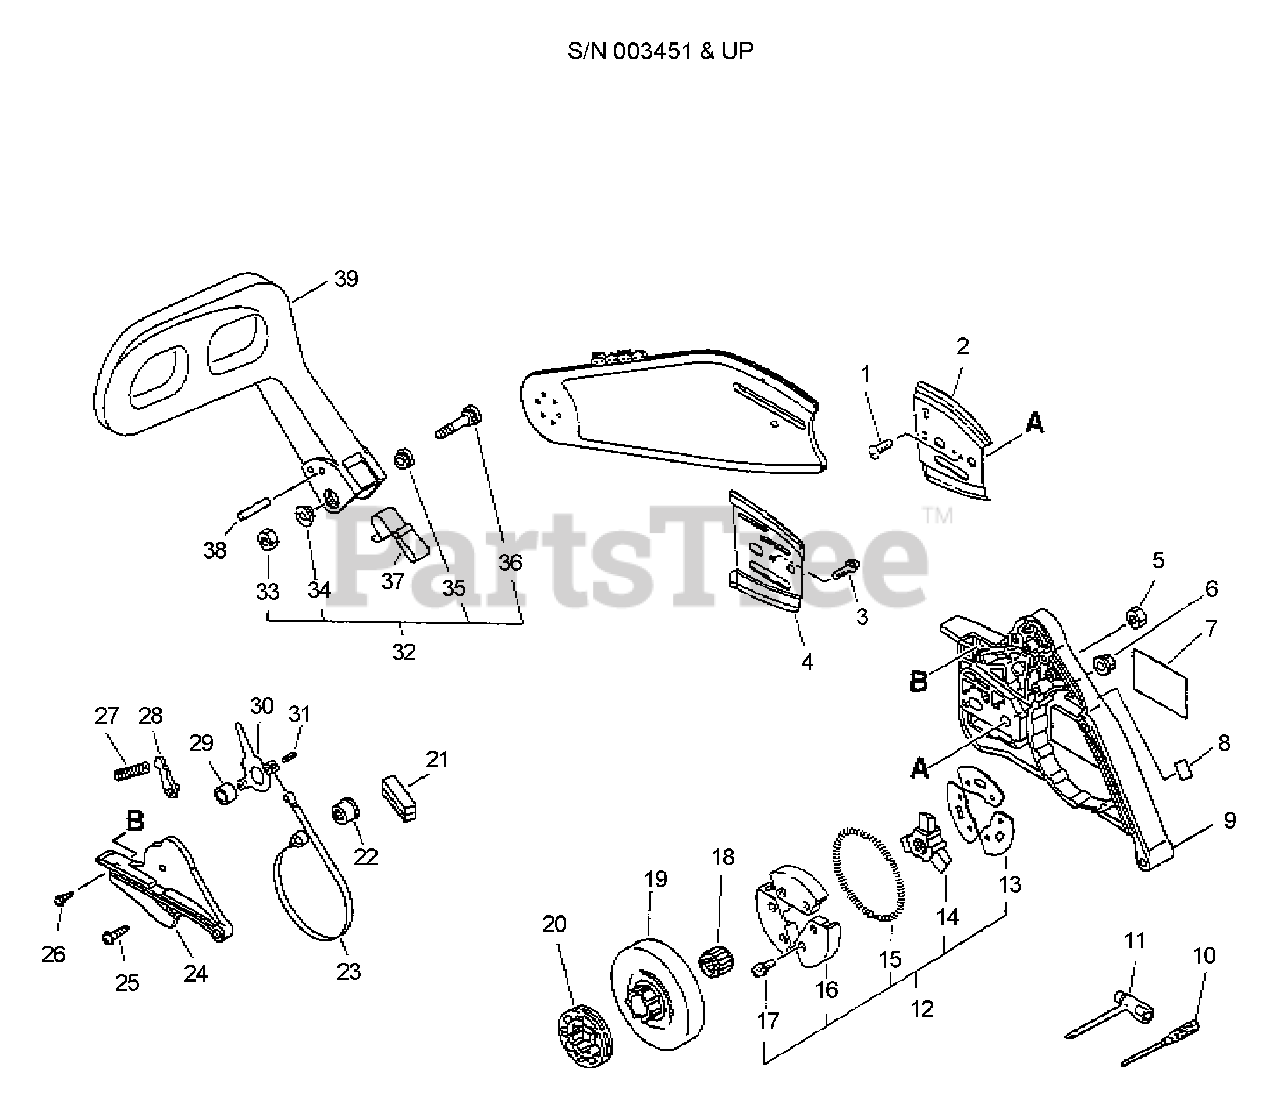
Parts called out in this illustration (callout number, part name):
1	SCREW 3×6
2	PLATE, GUIDE - OUTER
3	SCREW 4×8
4	PLATE, GUIDE - INNER
5	NUT 3 MM
6	NUT, FLANGE M8×1.25
7	LABEL, ECHO
8	LABEL, CAUTION
9	GUARD, SPROCKET
10	SCREWDRIVER, PHILLIPS
11	T-WRENCH 13×19×180
12	CLUTCH ASSY
13	PLATE, CLUTCH
14	HUB, CLUTCH
15	SPRING, CLUTCH
16	CLUTCH SHOE SET
17	BOLT 4×6
18	BEARING, NEEDLE
19	DRUM, CLUTCH
20	SPROCKET, RIM 3/8"×7T
21	SEAL, BRAKE
22	ADJUSTER, BRAKE
23	BAND, BRAKE
24	COVER, BRAKE
25	SCREW 3×18
26	SCREW 4×12
27	SPRING, BRAKE
28	STOPPER, BRAKE
29	SPACER 8×12×9
30	LEVER, BRAKE
31	PIN, SPRING 4×8.8
32	SCREW KIT
33	NUT, LOCK M5
34	COLLAR 5.3×10×13×L5
35	COLLAR 5
36	SCREW 5×35
37	SPRING, RETURN
38	PIN 3.5×26
39	LEVER, BRAKE
